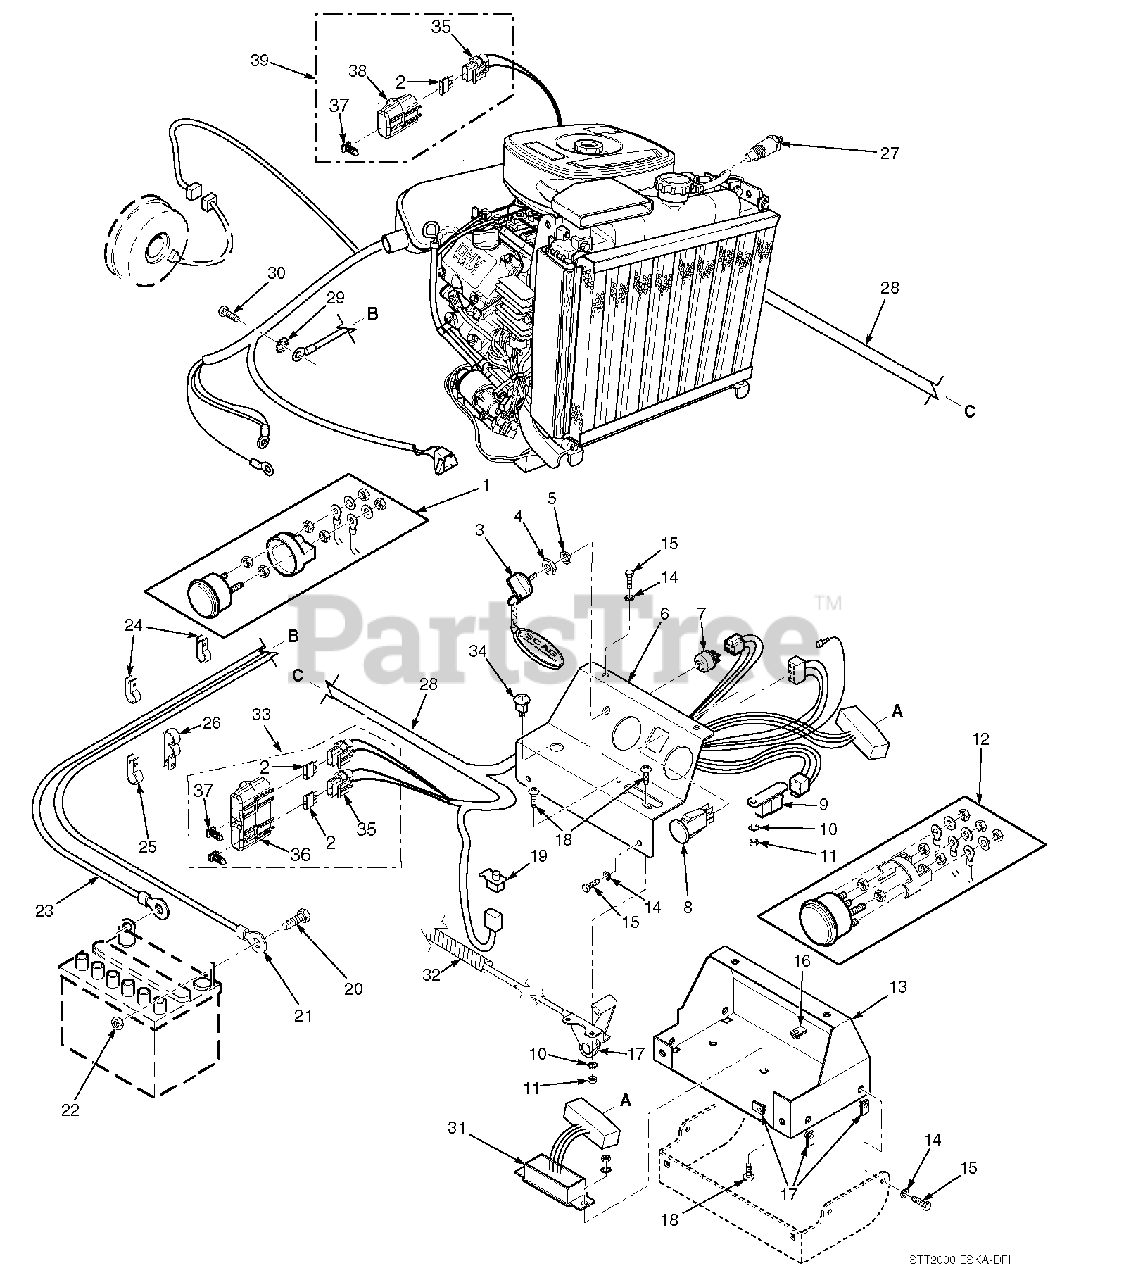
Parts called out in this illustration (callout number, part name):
1	Ammeter
2	Fuse, 20 AMP
3	Key, Ignition
4	Nut, Hex 5/8-32
5	Lockwasher, 5/8" Internal
6	Instrument Panel, Top w/Decals
7	Key Switch
8	Switch, PTO
9	Relay
10	Lockwasher, #10 External Tooth
11	Nut, Hex #10-32
12	Water Temp. Gauge
13	Base, Instrument Panel
14	Lockwasher, 1/4"
15	Bolt, Hex Head 1/4-20 x 3/4"
16	U-Nut, 1/4-20
17	Throttle Controls
18	Screw, Phillips Washer Head #10-32 x 1/2"
19	Switch, Interlock-Seat
20	Bolt, Hex Head 1/4-20 x 1/2"
21	Cable, Battery - Red
22	Nut, Hex 1/4-20
23	Cable, Battery - Black
24	Clamp, Cable 1/2" ID.
25	Clamp, Cable 3/4" ID.
26	Clamp, Cable
27	Sending Unit, Water Temp.
28	Wire Harness, STT Liquid-Cooled Digital Fuel Injection
29	Lockwasher, 5/16" External Tooth
30	Bolt, Hex Head M8-1.25 x 20mm
31	Electronic Module
32	Heatshield, Flexible
33	Double Fuse Assembly, Sealed
34	Indicator Light, Check Engine
35	Fuse Holder
36	Cover, Sealed Double
37	Clip, Wire
38	Cover, Sealed Single
39	Single Fuse Assembly, Sealed
